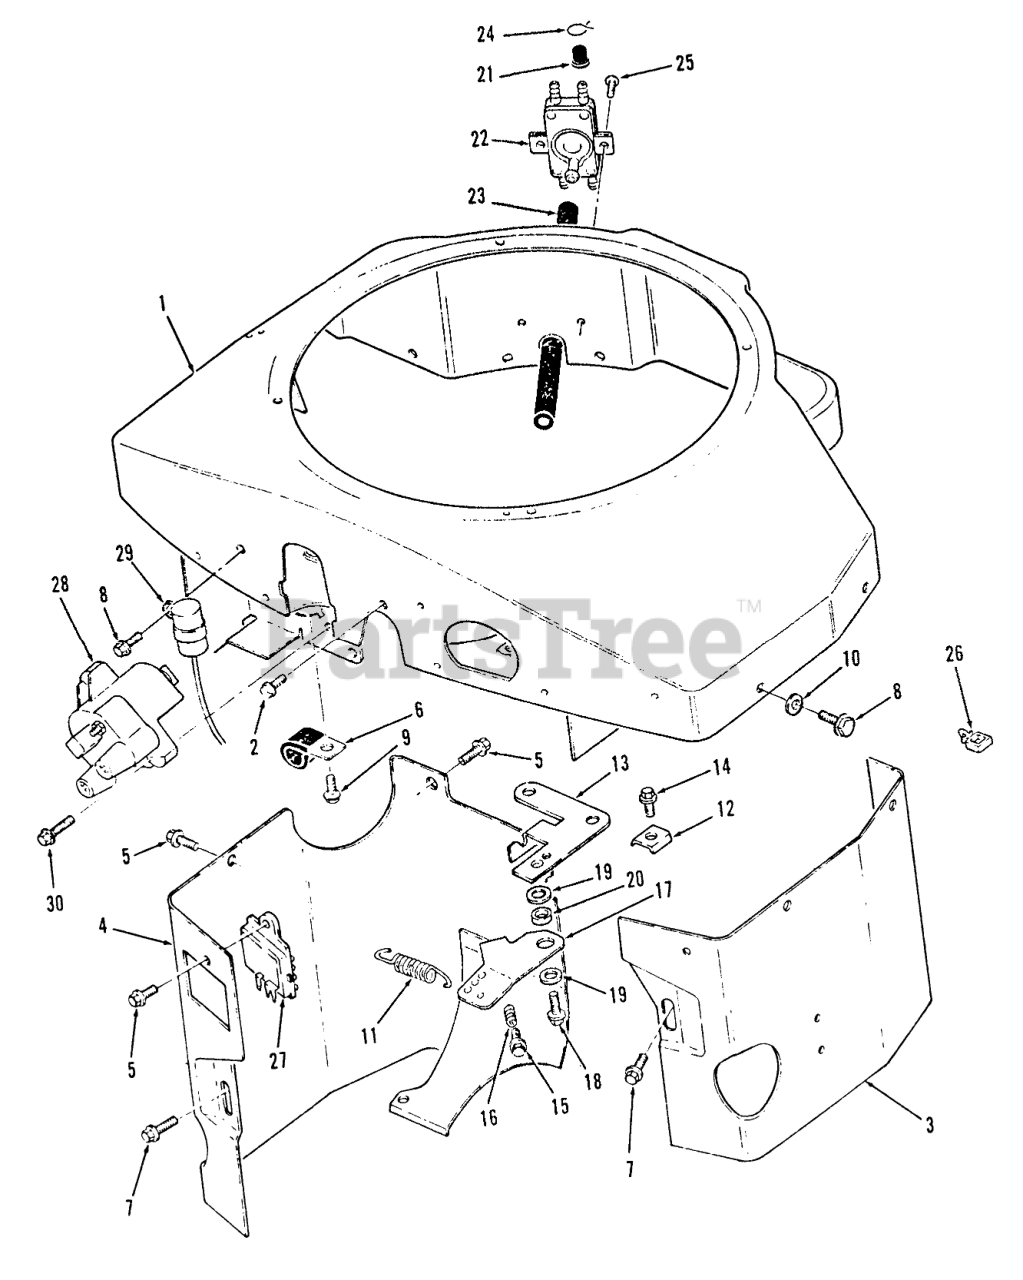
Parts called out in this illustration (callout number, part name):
1	Blower Housing
2	Bolt
3	Cylinder Air Housing
4	CYLINDER AIR HSG L H
5	Bolt
6	Clip
7	Bolt
8	Bolt
9	Bolt
10	Washer
11	Spring
12	Clamp
13	Bracket
14	Bolt
15	Bolt
16	Spring
17	Arm
18	Bolt
19	Screw
20	Bushing
21	Cap
22	FUEL-PUMP
23	Hose 11"
24	Clamp
25	Screw
26	Clip
27	Regulator
28	Coil-Ignition
29	Condenser
30	Bolt
